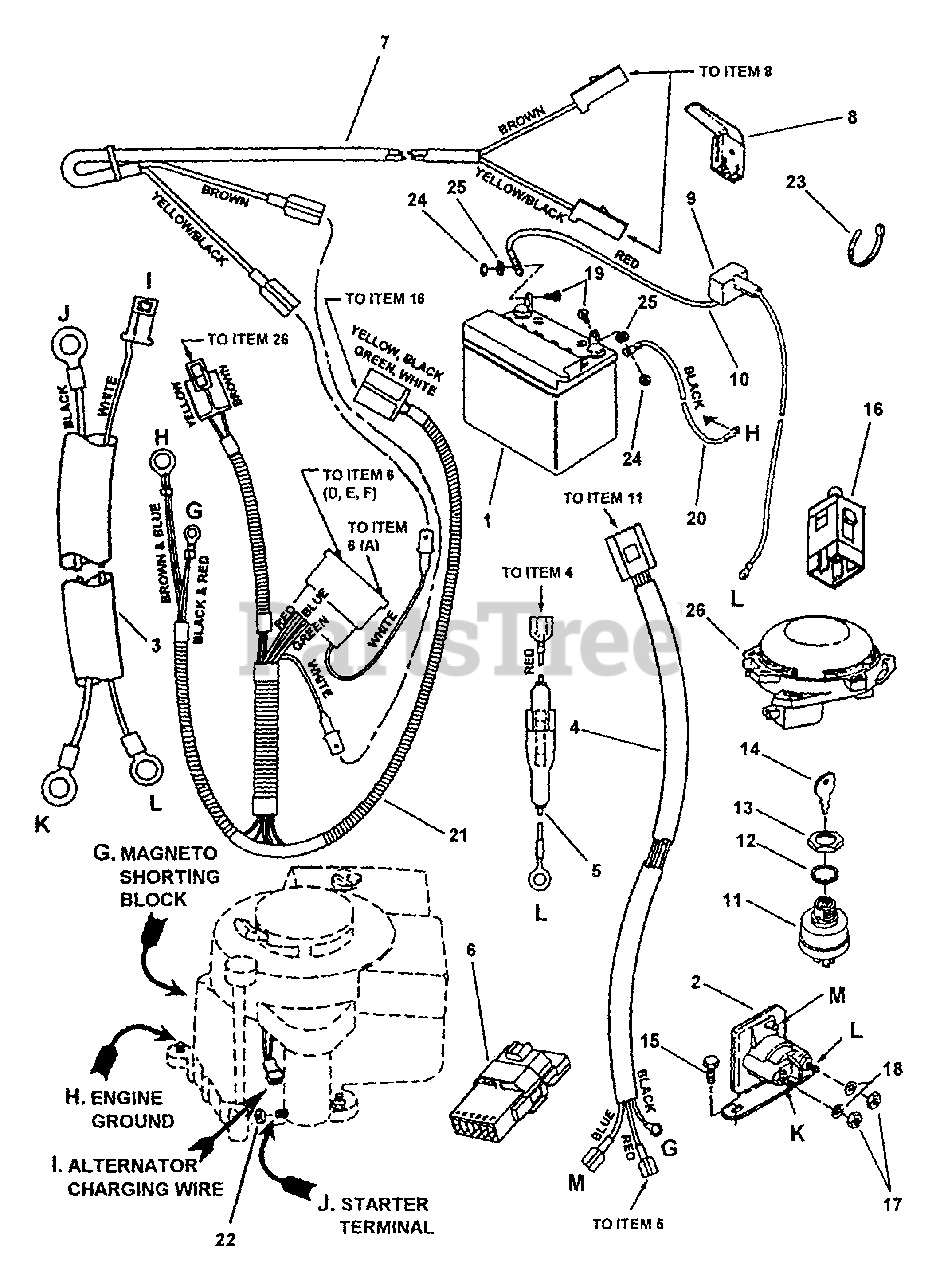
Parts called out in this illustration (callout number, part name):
1	KIT, Battery, 12V, U-1-7RS, 220CCA Dry Charge Snapper No Spill
2	SOLENOID
3	HARNESS, Starter Wiring (Briggs)
4	HARNESS, Ignition Wiring (Briggs)
5	HOLDER, Fuse
6	INTERLOCK Module (Briggs)
7	HARNESS, (Deck Interlock Wiring)
8	SWITCH, Deck Interlock (NO)
9	COVER, Battery Cable
10	CABLE, Positive (Red)
11	SWITCH, Ignition
12	WASHER, 5/8" Internal Tooth Lock
13	NUT, 5/8-32 Hex
14	KEY, Switch
15	SCREW, 1/4-20 x 1/2" Hex Washer Self-Tap
16	SWITCH, Operator Presence Control Traction (NC/NO)
17	NUT, 1/4-20 Hex
18	WASHER, 1/4 Internal Tooth Lock
19	SCREW, 1/4-20 x 5/8" Hex Head Cap
20	CABLE, Negative
21	HARNESS, Operator Presence Control Wire
22	NUT, 1/4-20 Hex
23	TIE, 7" Long Cable
24	NUT, 1/4-20 Hex Center Lock
25	RETAINER, Bolt
26	SWITCH, Seat (NC)
